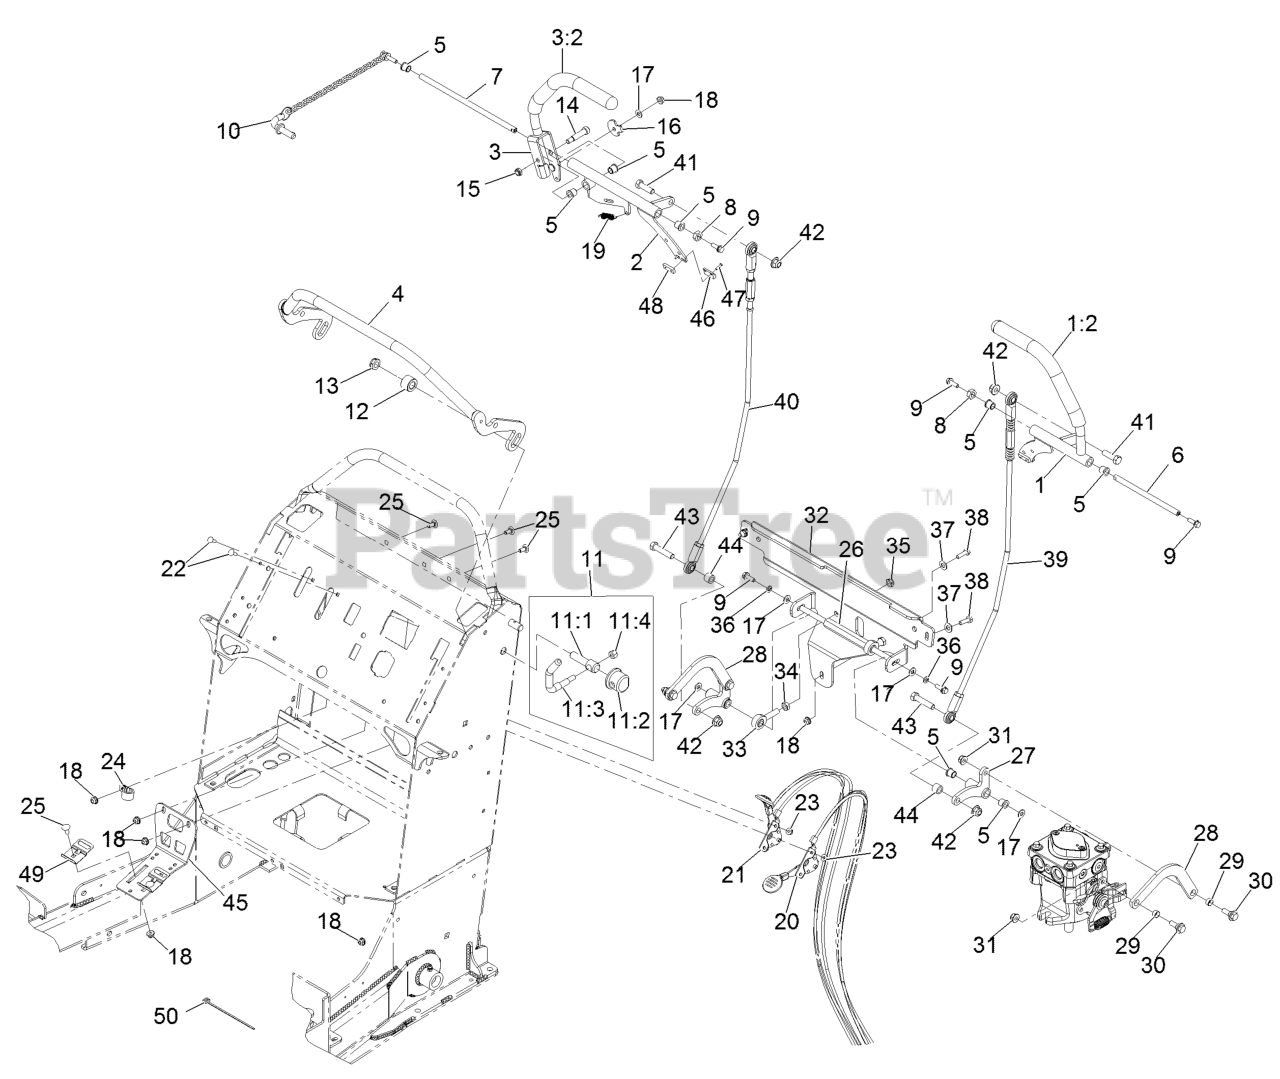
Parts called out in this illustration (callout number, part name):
1	LEVER ASM, LH
1:2	GRIP-HANDLE, CONTROL
2	MOTION CONTROL ASM-RH
3	LEVER ASM, RH
3:2	GRIP-HANDLE, CONTROL
4	TUBE ASM, FRONT SPEED CONTROL
5	BEARING
6	SHAFT-PIVOT, MOTION CONTROL
7	SHAFT-PIVOT, MOTION CONTROL
8	SPACER-SHAFT, DRIVE LEVER
9	SCREW-HHF
10	HOC PIN ASM
11	LEVER ASM
11:1	SCREW-LOCK
11:2	CAP-LOCK
11:4	NUT-LOCK, NI
12	SPACER-CLAMP
13	NUT-HEX
14	SCREW-HSH
15	NUT-LOCK, NI
16	CAM-LEVER
17	WASHER-FLAT
19	SPRING-EXTENSION
20	CONTROL-THROTTLE
21	CONTROL-CHOKE
22	BOLT-CARR
23	NUT-LOCK, FLANGE
24	CLAMP-CABLE
25	SCREW-CARR
26	SHAFT-BELLCRANK PIVOT
27	BELLCRANK-CONTROL, MOTION
28	LINK-BELLCRANK, PUMP
29	BUSHING-SLEEVE
30	SCREW-SHOULDER
31	NUT-HF, NI
32	BRACKET-BELLCRANK
33	BALLJOINT
34	NUT-HJ
35	NUT-HEX
36	SCREW-HH
37	WASHER-PLAIN
38	SCREW-HH
39	LINKAGE-TRACKING CONTROL,LH
40	LINKAGE-TRACKING CONTROL,RH
41	SCREW-HH
42	NUT-HF, NI
43	SCREW-HH
44	SPACER-WHEEL
45	BRACKET, REED SWITCH
46	ACTUATOR-SWITCH, REED
47	SCREW-HH
48	PLATE-TAPPED
49	CLAMP, REED SWITCH
50	TIE-CABLE
